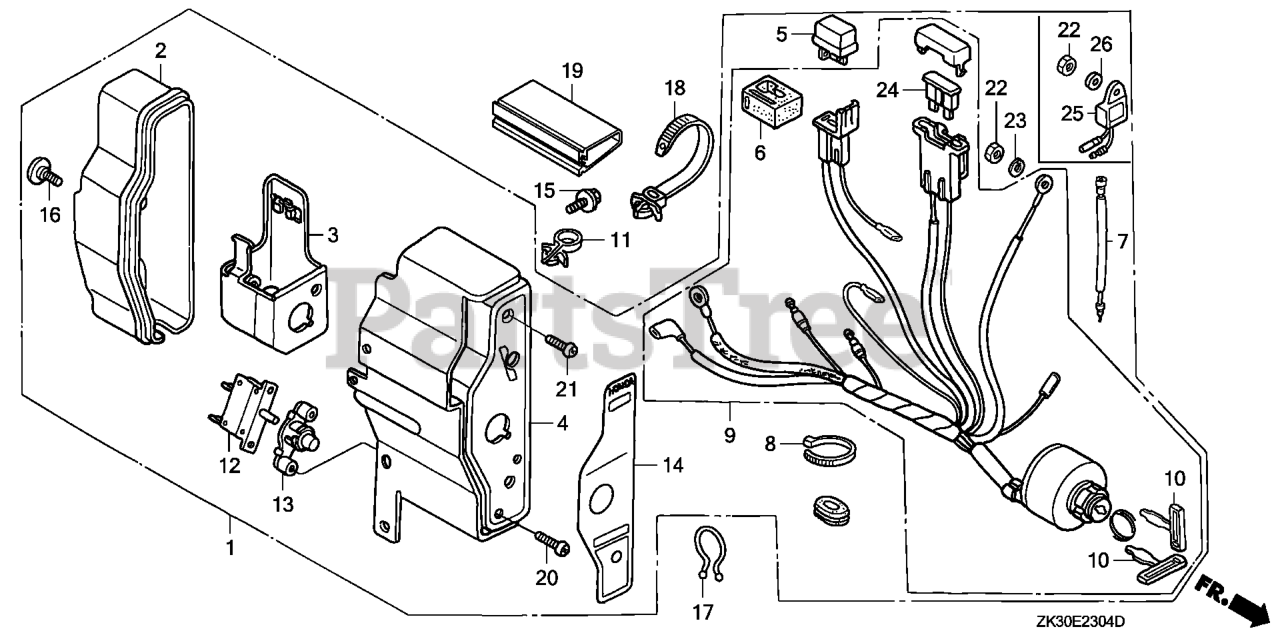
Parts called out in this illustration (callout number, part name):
1	BOX ASSY., CONTROL *R280* (ALERT) (POWER RED)
2	CASE, CONTROL
3	BRACKET, CASE MOUNTING
4	PANEL, CONTROL *R280* (POWER RED)
5	RECTIFIER ASSY., SILICON (SHINDENGEN)
6	SUSPENSION, CONNECTOR
7	SUB-WIRE HARNESS
8	BAND
9	SWITCH ASSY., COMBINATION
10	KEY
11	HOLDER, STOP SWITCH WIRE Use up to Engine SN 2056819.
12	PROTECTOR, CIRCUIT (1.0A)
13	LENS ASSY., PROTECTOR
14	MARK, CONTROL BOX (EXP)
15	BOLT, FLANGE (6X12) (CT200)
16	SCREW, SPECIAL (6X12)
17	CLIP, PURSE LOCK
18	STRAP, CABLE (118MM) *NH1L* (Honda Code 1170653). (BLACK)
19	TUBE, FASTENER (30)
20	SCREW, PAN (3X12)
21	SCREW, PAN (4X12)
22	NUT, HEX. (4MM)
23	WASHER, SPRING (4MM)
24	FUSE, BLADE (5A)
25	ALERT UNIT, OIL
26	WASHER, PLAIN (4MM)
